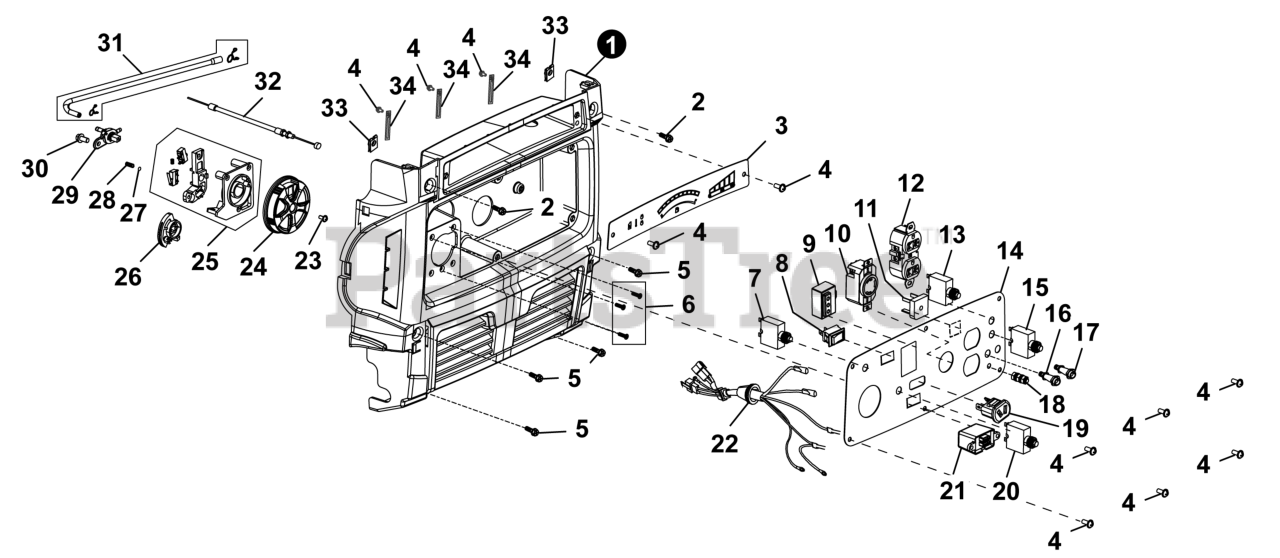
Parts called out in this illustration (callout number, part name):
1	SEAT, PANEL
3	PANEL, METER
6	SCREW, CROSS GROOVE PAN
7	SWITCH, RESET
8	SWITCH, AUTO THROTTLE
9	SWITCH, STARTER
10	SOCKET, POWER SUPPLY
11	BRIDGE, RECTIFICATION
12	SOCKET, POWER SUPPLY
13	BREAKER, CIRCUIT
14	PANEL, CONTROL
15	BREAKER, CIRCUIT
16	SOCKET, PARALELL (RED)
17	SOCKET, PARALELL (BLACK)
18	TERMINAL, GROUND BOLT
19	SOCKET, D.C. CHARGE
20	BREAKER, CIRCUIT
21	SOCKET, USB PORT
22	HARNESS, WIRING
25	ASSY., SWITCH
26	COVER, BOARD
27	BALL, STEEL
28	SPRING, STOPPER ADJUSTING
29	VALVE, FUEL SHUT OFF
31	HOSE, FUEL
32	CABLE, CHOKE
